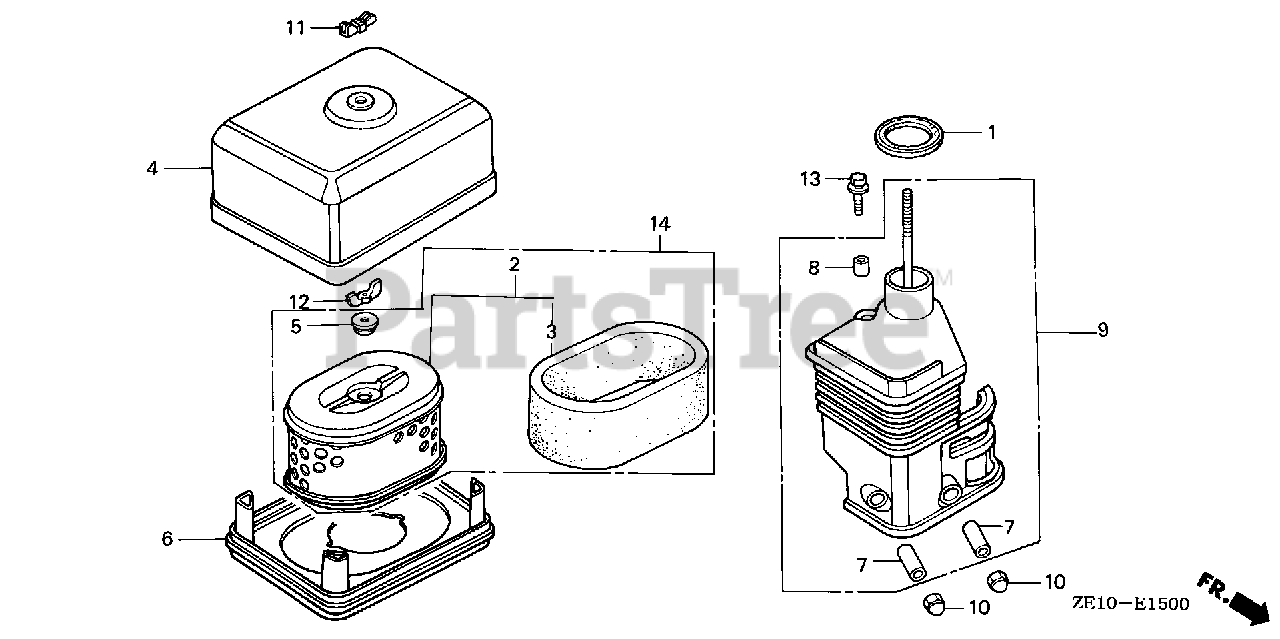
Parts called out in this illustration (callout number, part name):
1	GASKET, ELBOW
2	ELEMENT, AIR CLEANER (DUAL) Use up to Engine SN 2115700.
3	FILTER (OUTER)
4	COVER, AIR CLEANER (DUAL)
5	GROMMET, AIR CLEANER
7	COLLAR, AIR CLEANER Use up to Engine SN 1786084.
7	COLLAR, AIR CLEANER
8	COLLAR B, AIR CLEANER
9	ELBOW, AIR CLEANER
9	ELBOW, AIR CLEANER Use up to Engine SN 1220569.
10	NUT, CAP (6MM)
11	NUT, AIR CLEANER COVER (DACRO COATING)
12	NUT, TOOL BOX SETTING
13	BOLT-WASHER (6X20)
14	ELEMENT, AIR CLEANER (DUAL)
